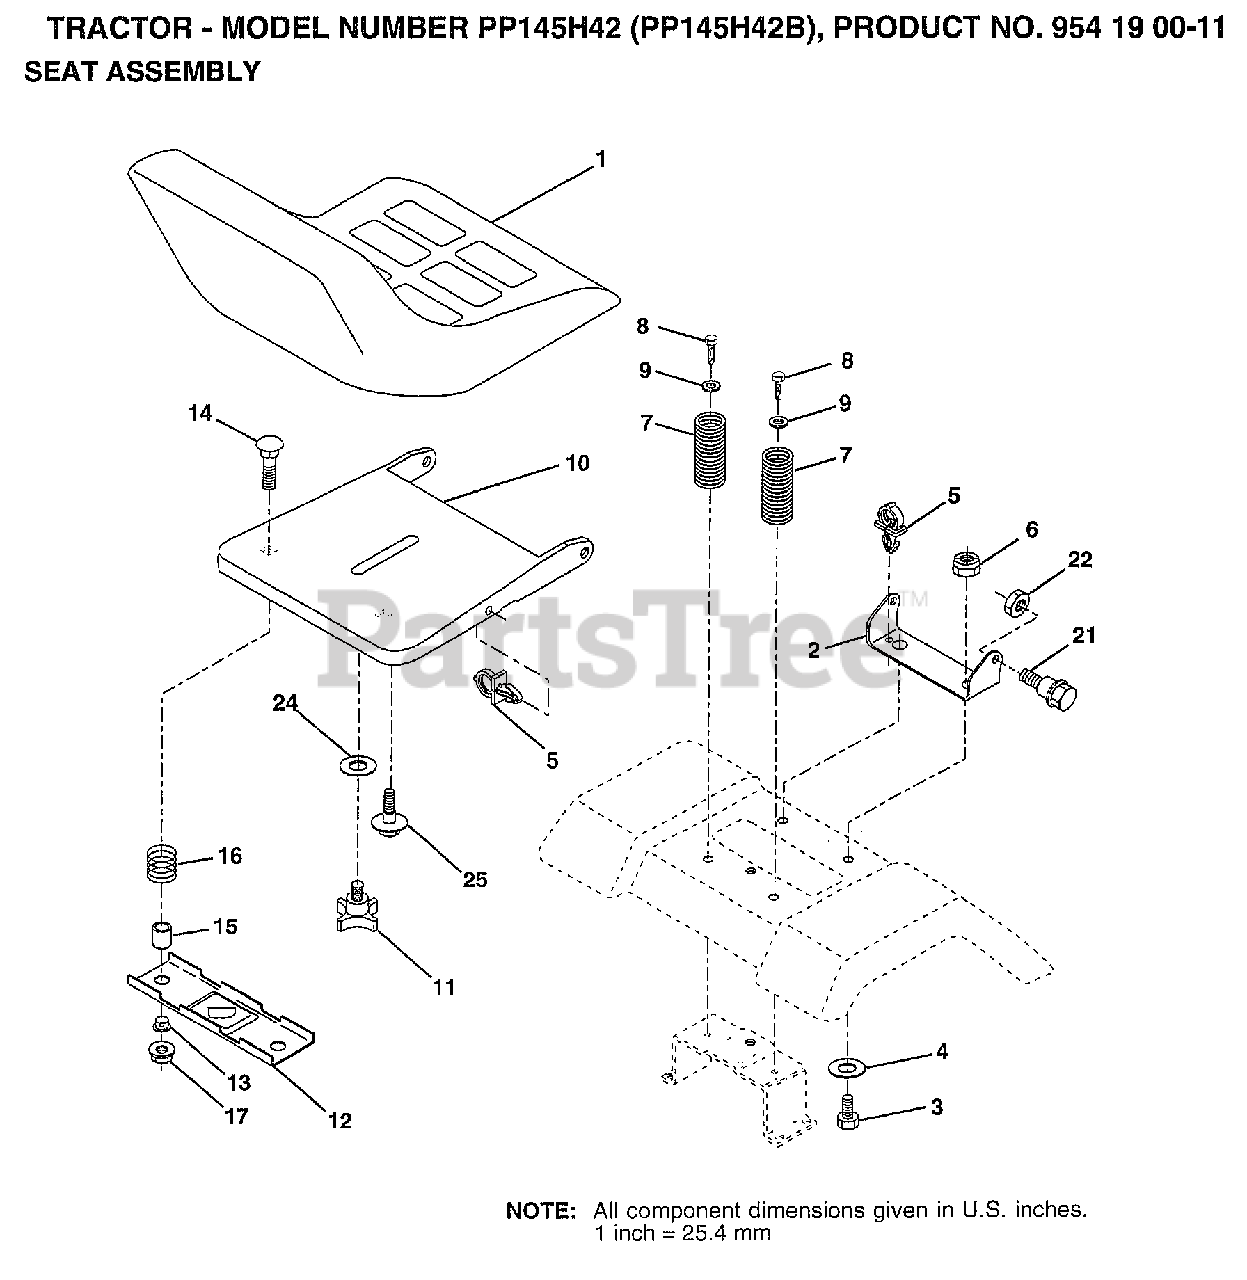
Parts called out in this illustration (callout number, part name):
1	SEAT.2400/1416.BK
2	BRACKET PVT SEAT
3	BOLT
4	WASHER PM
5	CLIP.PUSH-IN.HING
6	NUT
7	SPRING COMPRESSIO
8	SCREW GTV
9	WASHER
10	PAN-SEAT
11	"KNOB 1/2"" YT"
12	BRKT SWITCH
13	BUSHING
14	BOLT-RD HD SQ NK
15	SPLIT SPACER
16	SPRING
21	"BOLT,SHOULDER"
22	NUT
24	WASHER
25	"BOLT,SHOULDER"
